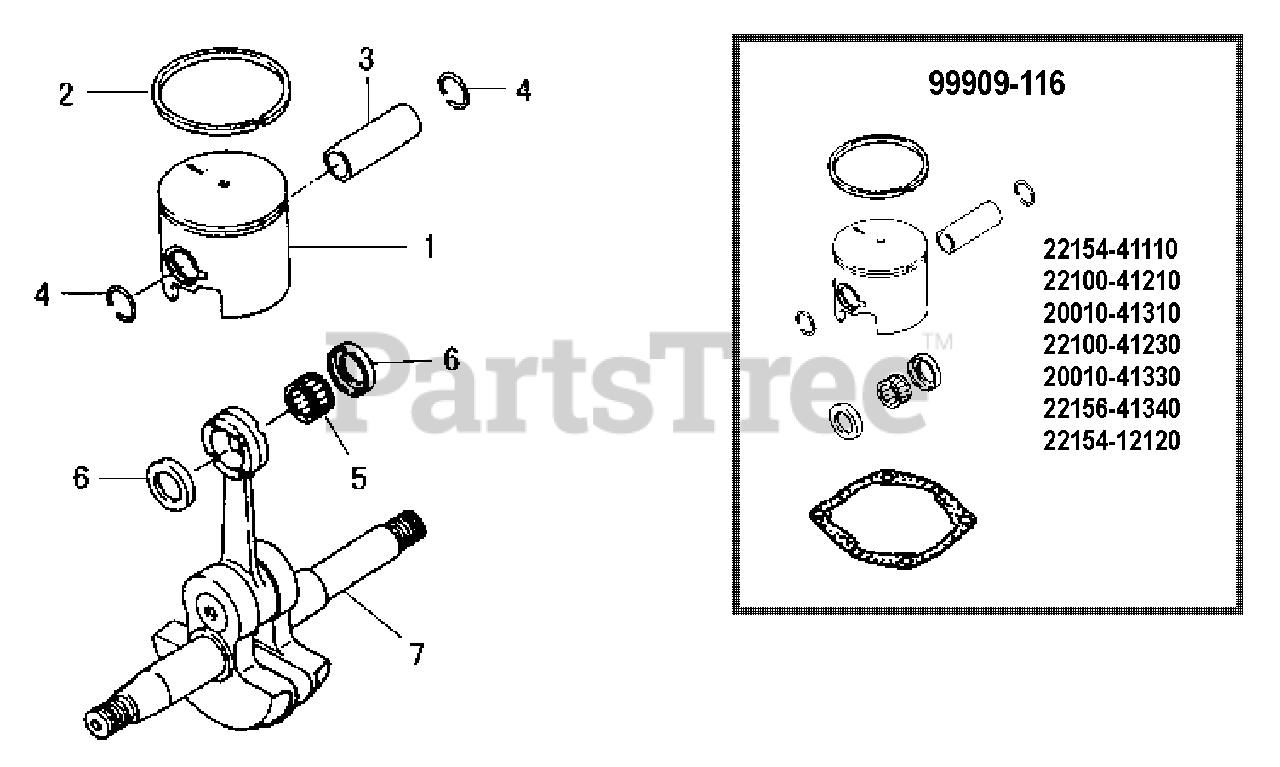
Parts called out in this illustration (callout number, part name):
1	PISTON
2	RING, PISTON
3	PIN, PISTON
4	RING, RETAINING
5	BEARING, NEEDLE
6	SPACER, PISTON
7	CRANKSHAFT ASSY
99909-116	PISTON KIT
